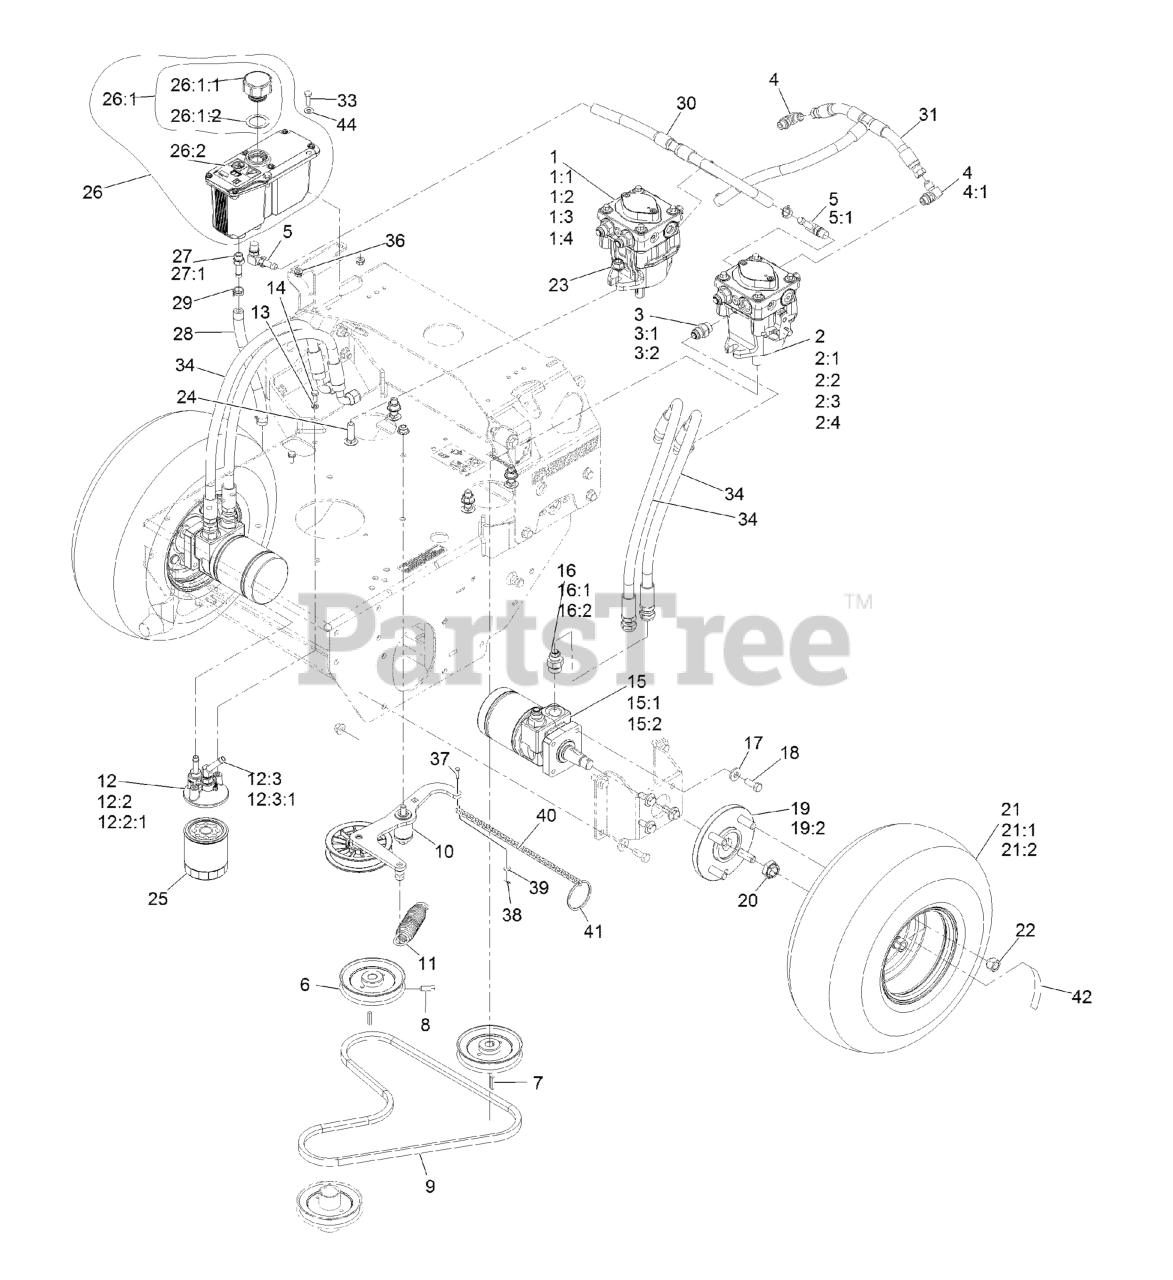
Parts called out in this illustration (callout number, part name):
1	RH HYD PUMP ASM
1:1	INPUT SHAFT KIT
1:2	BEARING-THRUST
1:3	CYLINDER BLOCK KIT
1:4	SEAL OVERHAUL KIT
2	LH HYD PUMP ASM
2:1	INPUT SHAFT KIT
2:2	BEARING-THRUST
2:3	CYLINDER BLOCK KIT
2:4	SEAL OVERHAUL KIT
3	FITTING-STRAIGHT
4	FITTING-ELBOW, 90 DEG
4:1	O-RING
5	FITTING-ELBOW, 90
5:1	O-RING
6	SHEAVE ASM
8	SCREW-SET, SQH
9	BELT
10	ASM, PUMP IDLER
11	SPRING-EXTENSION
12	ASM, FILTER HEAD
12:2	ADAPTER-STRAIGHT
12:2:1	O-RING
12:3	FITTING-BARBED, 45 DEG
12:3:1	O-RING
13	WASHER-LOCK
14	SCREW-HH
15	HYD MOTOR ASM
15:1	SEAL KIT
15:2	BEARING AND SEAL KIT
16	FITTING-STRAIGHT
16:1	O-RING
17	WASHER-BELLEVILLE
18	SCREW-HH
19	WHEEL HUB ASM
19:2	STUD-WHEEL
20	NUT-LOCK
21	WHEEL AND TIRE ASM
21:1	TIRE-TURFMASTER
21:2	RIM-WHEEL
22	NUT-LUG
23	NUT-HF, NI
24	BOLT-CARR
25	FILTER-25 MICRON, BI-DIRE
26:1	Reservoir-HYD
26:1:1	Cap-Reservoir, HYD
26:1:2	GASKET-CAP
26:2	DECAL-WARNING
27	ADAPTER-STRAIGHT
27:1	O-RING
28	HOSE-CHARGE
29	CLAMP-HOSE
30	HOSE-CASE DRAIN
31	HOSE-CHARGE
33	SCREW-HH
34	HYD HOSE ASM
36	NUT-HHF
37	PIN-CLEVIS
38	PIN-HAIR
39	WASHER-PLAIN
40	CHAIN-LINK, TWIST
41	RING-SPLIT
42	DECAL-TORQUE WHEEL LUG-HU
44	WASHER-FLAT
